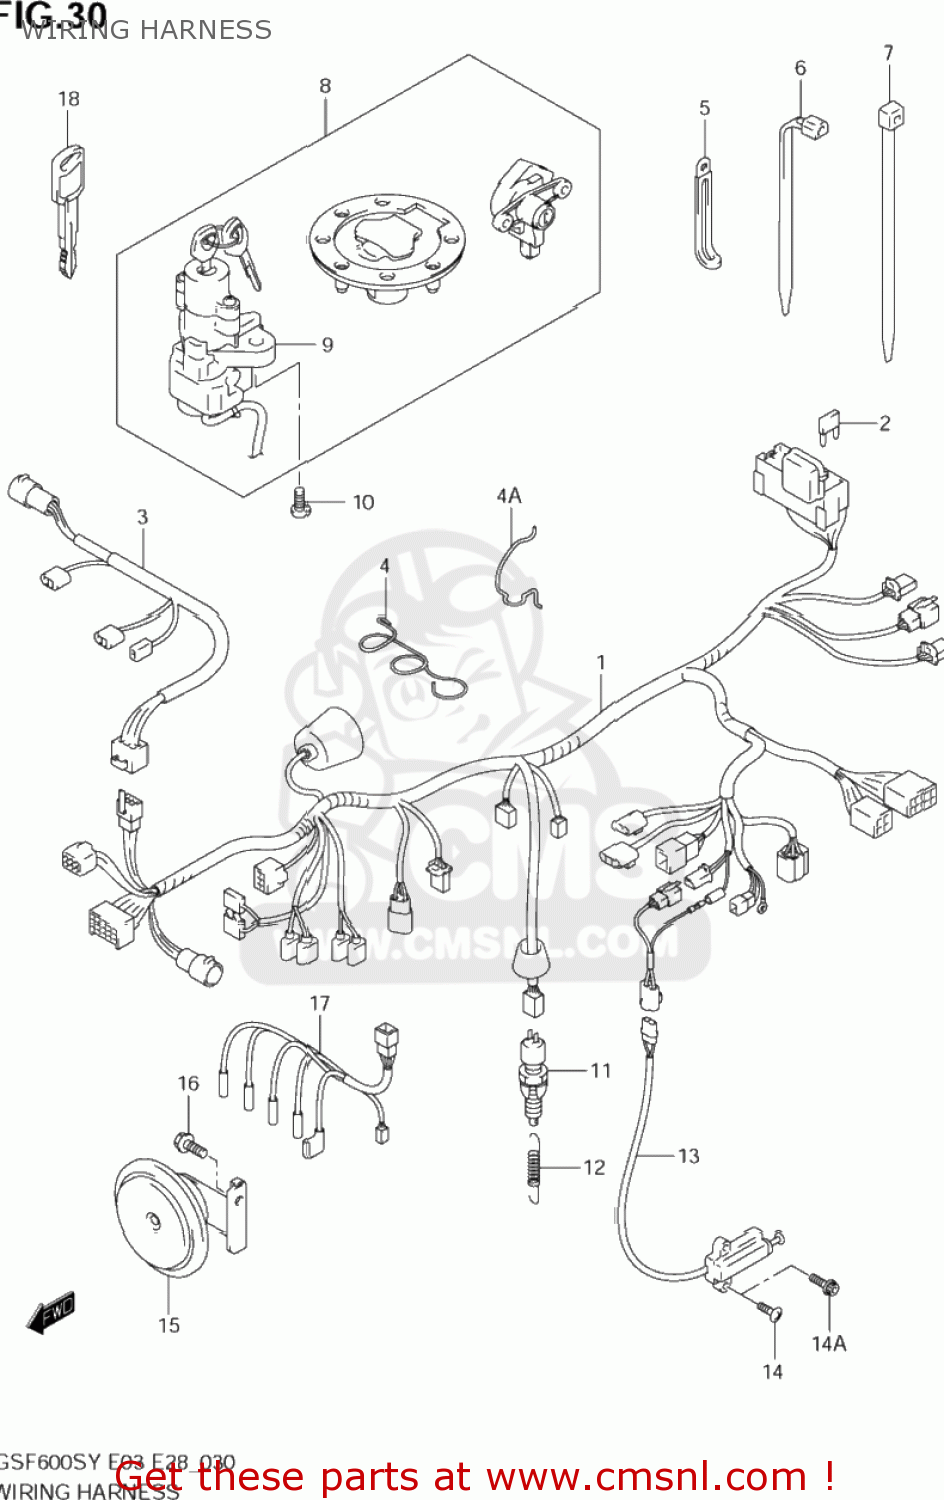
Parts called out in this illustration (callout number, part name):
1	HARNESS,WIRING
2	FUSE(10A)
3	HARNESS,WIRING NO.2
4	GUIDE,WIRING HARNESS
4A	GUIDE,WIRING HARNESS
5	CLAMP(L:65)
6	CLAMP(L:90)
7	CLAMP(L:145)
8	LOCK SET
9	LOCK ASSY,STEERING
10	BOLT(8X20)
11	SWITCH ASSY,STOP LAMP
12	SPRING
13	SWITCH ASSY,SIDE STAND
14	SCREW
14A	BOLT
15	HORN ASSY
16	BOLT
17	WIRE,CARB HEATER LEAD
18	KEY,BLANK
